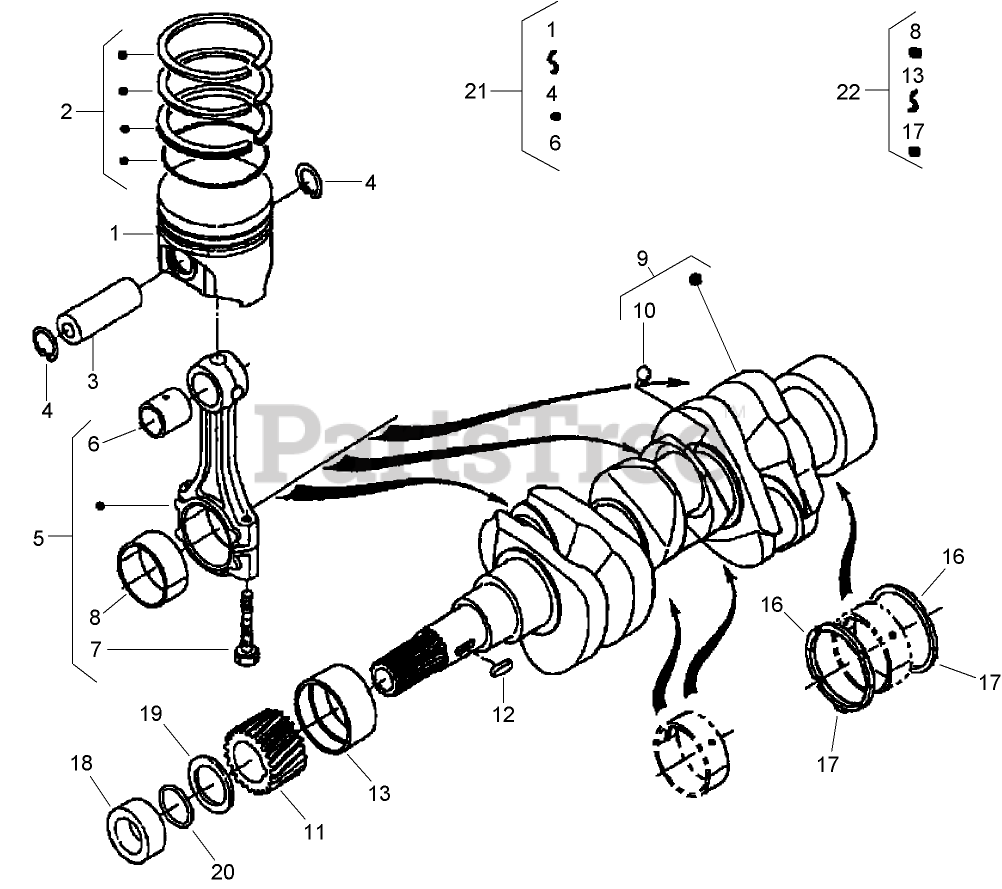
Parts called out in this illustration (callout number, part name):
1	PISTON
2	PISTON RING ASM (STD)
2	PISTON RING ASM (+.25MM)
3	PIN-PISTON
4	CIRCLIP-INTERNAL
5	CONNECTING ROD ASM
6	BUSHING-PIN, PISTON
7	BOLT-ROD, CONNECTING
8	METAL-CRANKPIN (-0.20mm)
8	METAL-CRANKPIN (-0.40mm)
8	METAL-CRANKPIN (STD)
9	CRANKSHAFT
11	GEAR-CRANKSHAFT
12	KEY-FEATHER
13	METAL-CRANKSHAFT (STD)
13	METAL-CRANKSHAFT (-.0.20MM)
13	METAL-CRANKSHAFT (-0.40MM)
16	METAL-SIDE (STD)
16	METAL-SIDE (+0.20MM)
16	METAL-SIDE (+0.40MM)
17	METAL-SIDE (STD)
17	METAL-SIDE (+0.2MM)
17	METAL-SIDE (+0.4MM)
18	COLLAR-CRANKSHAFT
19	SLINGER-OIL
20	O-RING
21	PISTON KIT (STD)
21	PISTON KIT (+.25MM)
22	ENGINE METAL KIT
